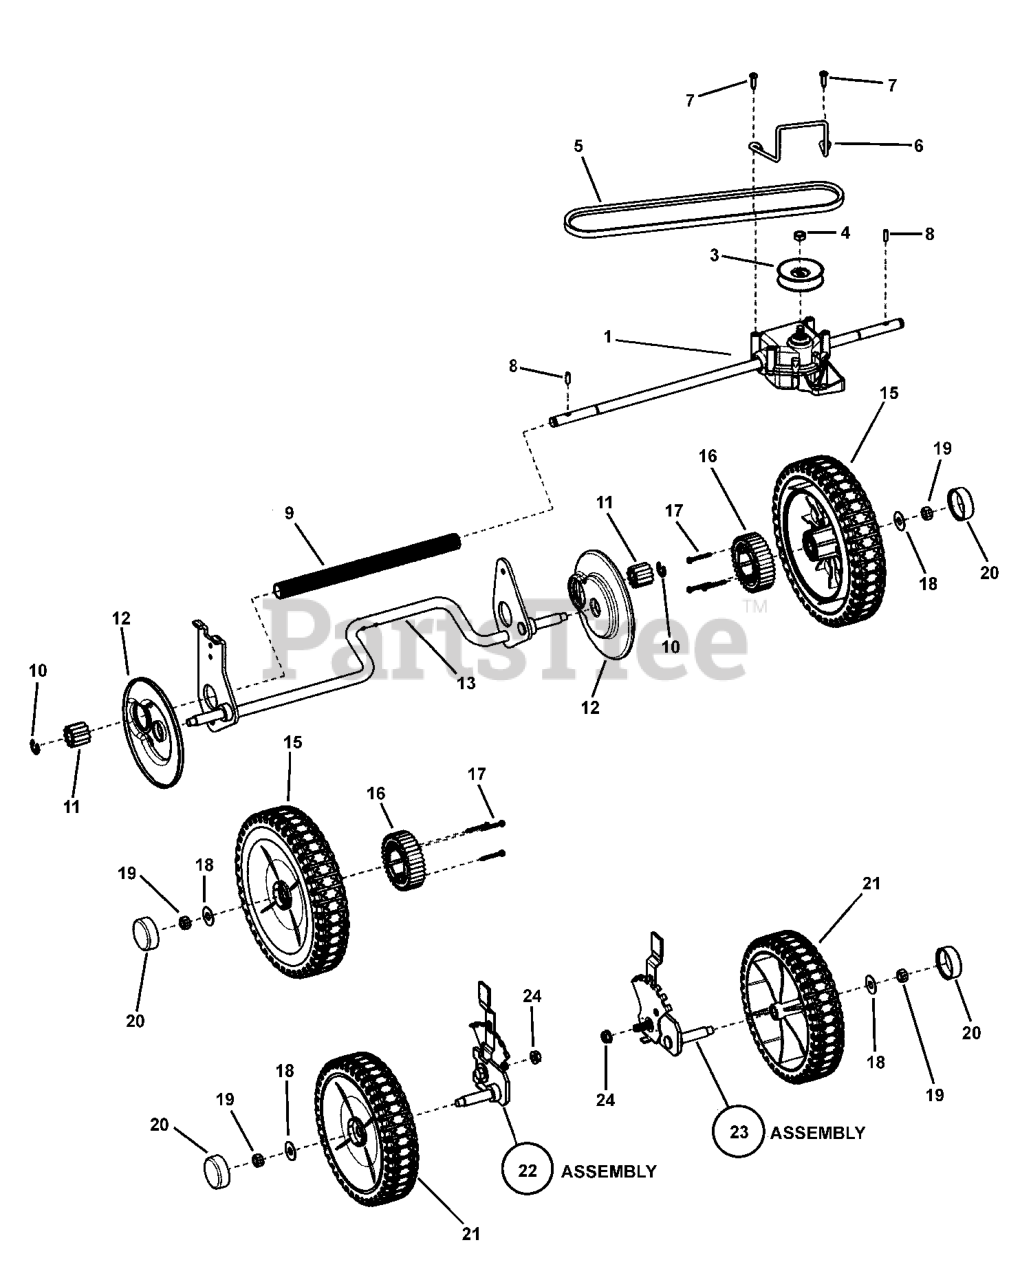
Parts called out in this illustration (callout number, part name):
1	TRANSMISSION, 21" WBM, RD
3	PULLEY, TRANS VAR SPD LC WBM
4	NUT, JAM, 3/8-16 BLK
5	BELT, 3L, TRACTION DRIVE, 21" PIVOT HANDLE
6	BELT GUIDE, TRANSMISSION
7	SCREW, #10-16 X 3/4, COMBO
8	PIN, AXLE
9	SHIELD, AXLE
10	RETAINING RING
11	GEAR, PINION
12	SHIELD DUST, 21" WBM, RD
13	WELDMENT, REAR CROSSBAR 21" WBM, RD
15	WHEEL ASSEMBLY, W/BEARING 9" ST TRD, BRUTE
16	GEAR, EXTERNAL WHEEL
17	SCREW, #8 X 1-1/4, HI-LO
18	WASHER, FLAT, 1" OD X .387 ID
19	NUT, 3/8-16 YZ
20	HUBCAP, ROUND, BLACK
21	WHEEL, 8"X 2" IDLE, W/DB TRD, BRUTE YELLOW
22	HEIGHT OF CUT ASSEMBLY, RF, BRUTE 21, 7 POSITION
23	HEIGHT OF CUT ASSEMBLY, LF, BRUTE 21, 7 POSITION
24	NUT, 3/8-16, BRIGHT ZINC
